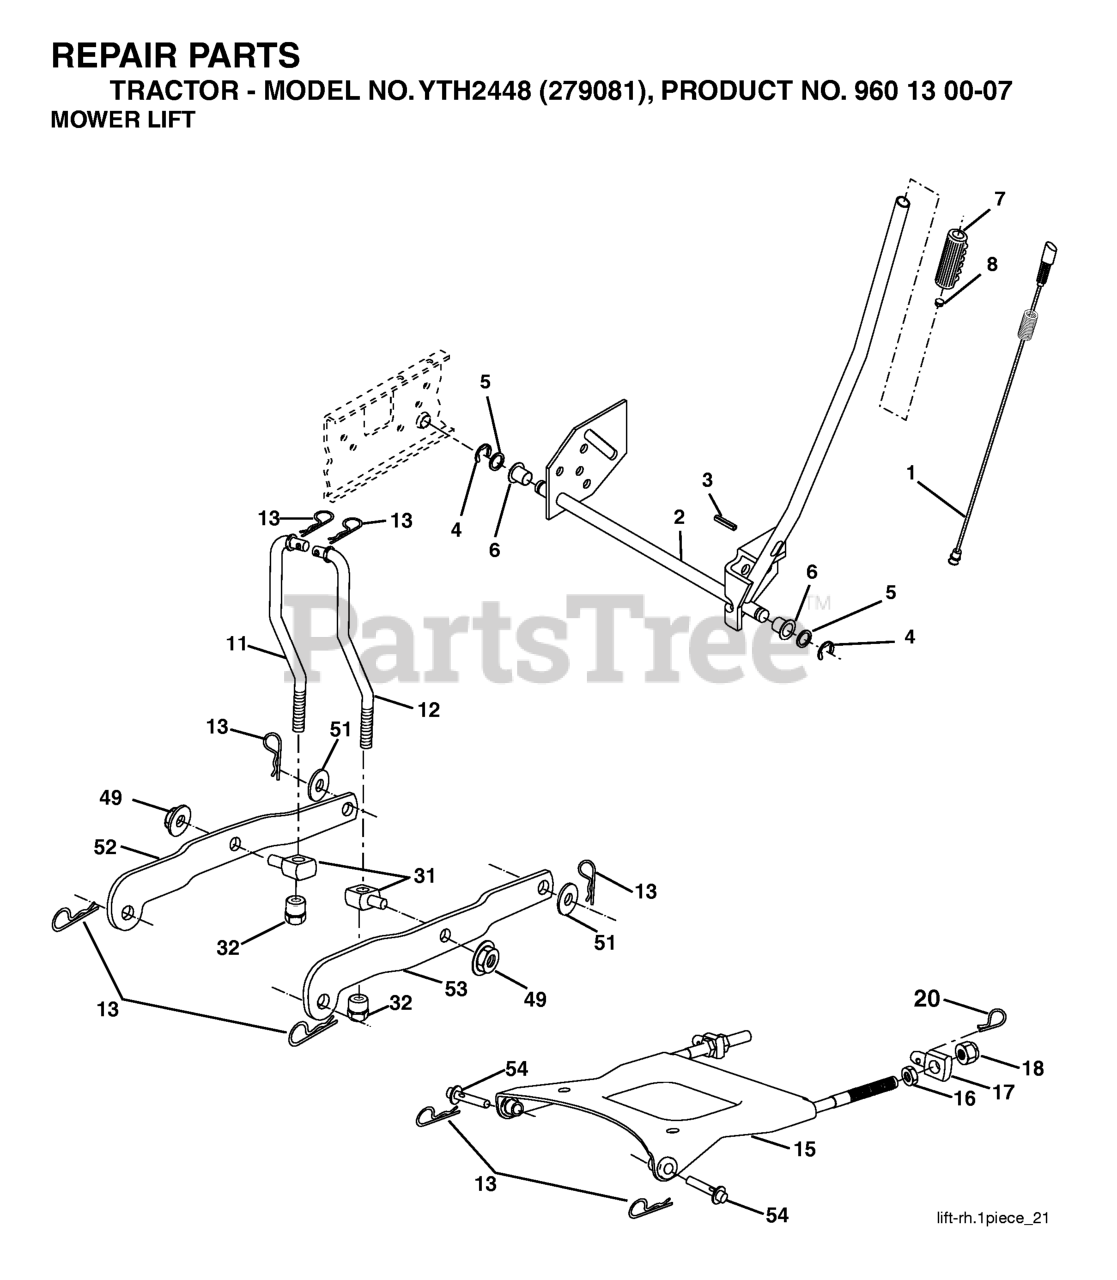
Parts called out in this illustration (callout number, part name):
1	WIRE ASM INNER W/ PLUNGER LT
2	SHAFT ASM R HANDLE
3	PIN GROOVE.
4	RETAINING RING LT
6	BEARING.NYLON
7	GRIP HANDLE
8	PLUNGER BUT KIT
11	LIFT LINK LH
12	LIFT LINK RH
13	RETAINER-SPRNG RB
15	PLATE ASM SUSP FRONT
16	NUT.HEX.JAM.1/2-13
18	NUT.LK.W/WSH.1/2.
20	SPRING RETAINER
32	NUT, LIFT LINK 7/16-20
49	NUT
51	Washer 1 17/32 X 7/8 X 16 Ga
52	ARM SUSP. REAR LH
53	ARM SUSP REAR RH
54	PIN.FLANGE
